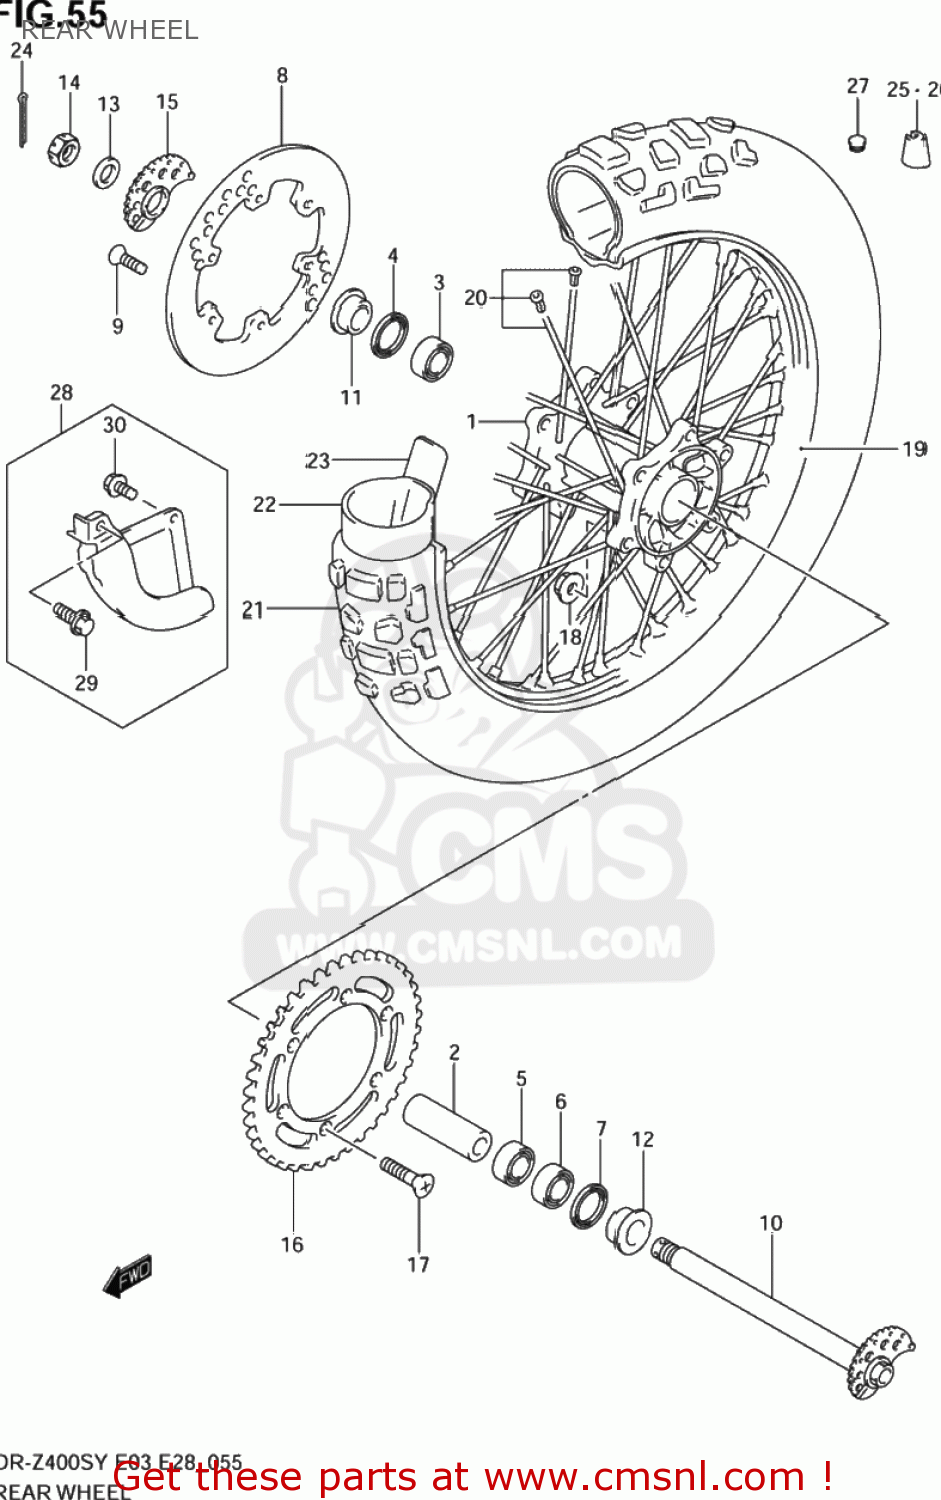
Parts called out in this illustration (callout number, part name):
1	HUB,RR WHEEL
2	SPACER,RR HUB BEARING
3	BEARING
4	SEAL(29X42X6)
5	BEARING
6	BEARING
7	SEAL,OIL(29X47X6)
8	DISC,RR BRAKE
9	SCREW
10	AXLE,RR
11	SPACER,RR AXLE
12	SPACER,RR AXLE
13	WASHER(19X32X3.2)
14	NUT
15	ADJUSTER,CHAIN,R
16	SPROCKET,RR(44T,S45C)
17	BOLT(8X30.5)
18	NUT
19	RIM,RR WHEEL(18X2.15 AL)
20	SPOKE SET,RR WHEEL
21	TIRE,RR(120/90-18 65P)
22	TUBE ASSY,WHEEL INNER
23	PROTECTOR,WHL INR TUBE
24	PIN,COTTER
25	BALANCER,WHEEL
26	BALANCER,WHEEL (30G)
27	CAP(OD:12)
28	COVER SET,RR BRAKE DISC
29	BOLT
30	BOLT
